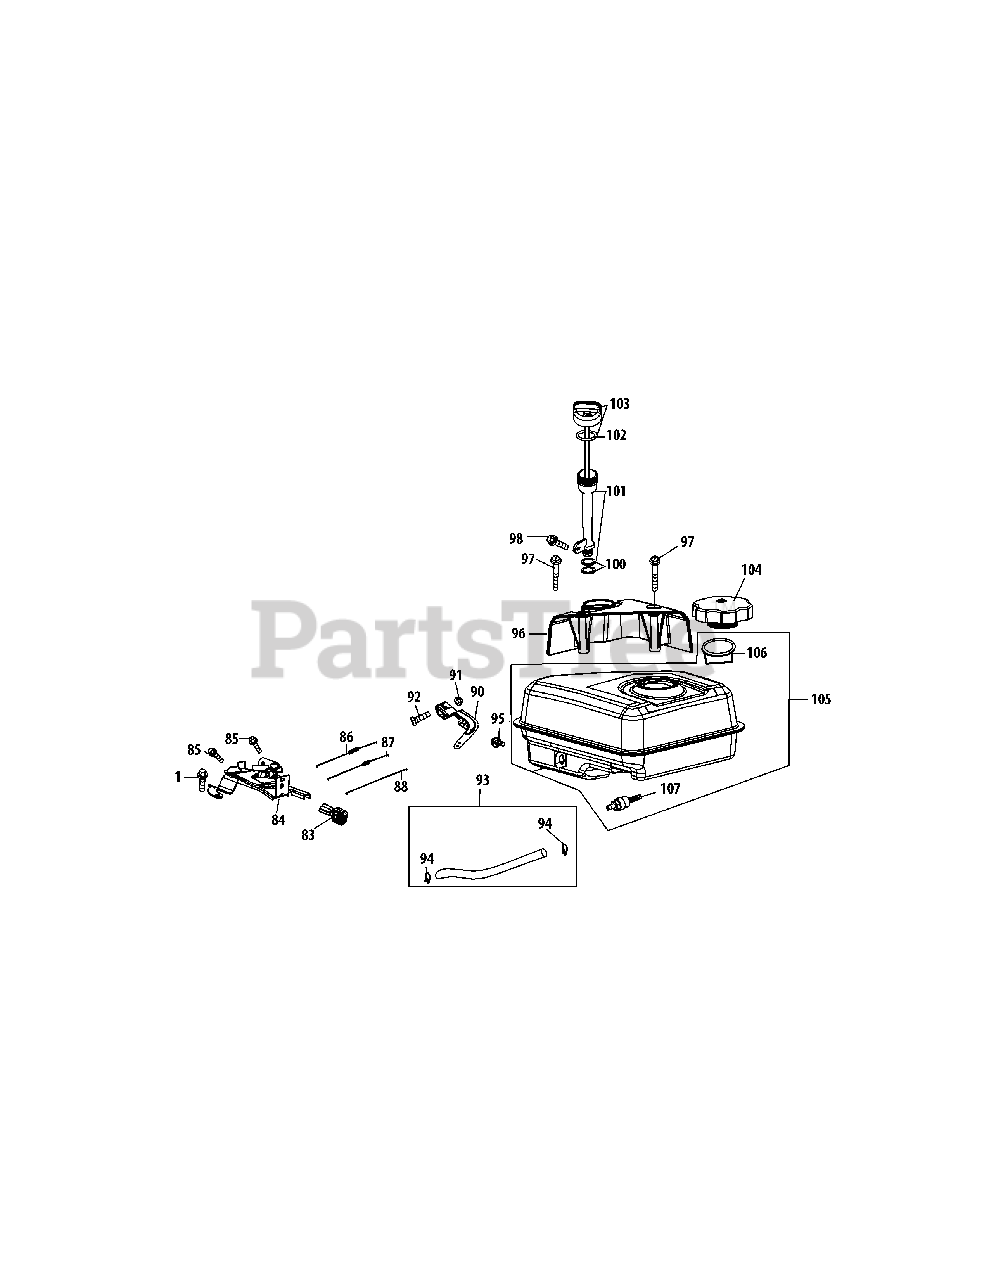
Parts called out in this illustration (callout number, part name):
1	Bolt M6×16
83	Throttle Control Knob
84	Primer Bracket
85	Bolt M6×12
86	Governor Spring
87	Throttle Linkage Spring
88	Throttle Linkage
90	Governor Arm Bracket
91	Nut M6
92	Governor Arm Bolt
93	Fuel Line Kit
94	Fuel Hose Clamp
95	Bolt M6×12
96	Dipstick Decoration Cover
98	Bolt M6×12
100	Oil Fill Tube O-Ring
101	Oil Fill Tube Assembly (Incl. 100)
102	Dipstick O-Ring
103	Dipstick Assembly (Incl. 102)
104	Fuel Cap Assembly
105	Fuel Tank Assembly
106	Fuel Filter
107	Fuel Tank Nipple
